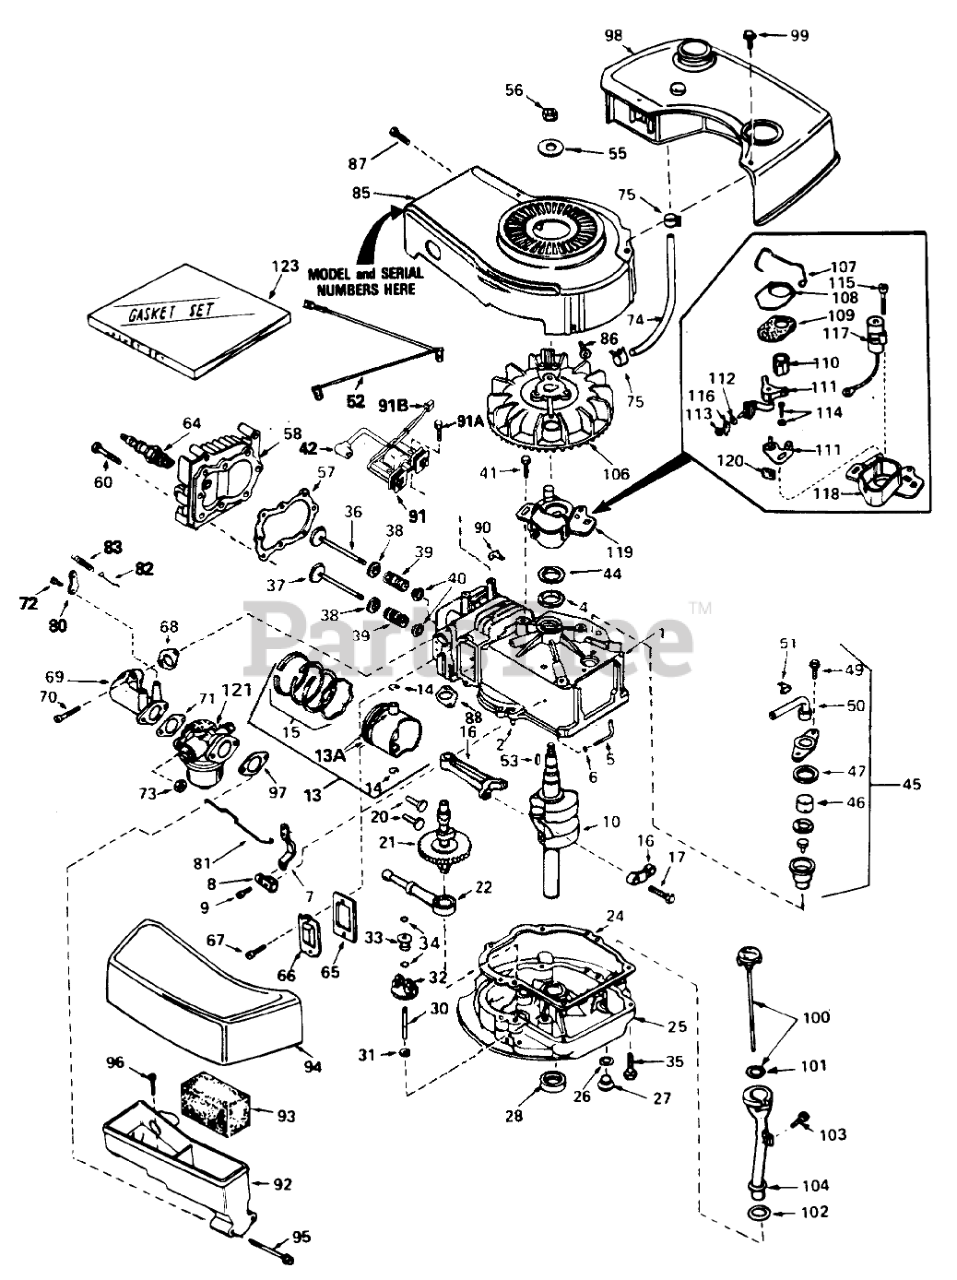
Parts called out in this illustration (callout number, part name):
1	Cyiinder Assy. (Incl. Ref. #2, 4 & 105)
2	Pin-Dowel
4	Seal-Oil
5	Rod, Governor (Incl. Ref. #6)
6	Washer-Flat
7	Governor Lever
8	Clamp-Lever, Governor
9	Screw
10	Crankshaft
13	Piston, Pin & Ring Assy. (Std.)(Incl. Ref. #13A, 14 & 15)
13	Piston,Pin & Ring Assy. (.010 over-size)(Incl. Ref. #13A, 14 & 15)
13	Piston, Pin & Ring Assy. (.020 over-size)(Incl. Ref. #13A, 14 & 15)
13A	Piston & Pin Assy. (Std.)(Incl. Ref. #14)
13A	Piston & Pin Assy. (.010 over-size)(Incl. Ref. #14)
13A	Piston & Pin Assy. (.020 over-size)(Incl. Ref. #14)
14	Ring-Retaining, Piston Pin
15	Ring Set Piston (Std.)
15	Ring Set Piston (.010 Oversize)
15	Ring Set Piston (.020 Oversize)
16	Rod Assy., Connecting (Incl. Ref. #17)
17	Bolt-Rod, Connecting
20	Lifter-Valve
21	Camshaft(Mech.Comp. Release)
22	Oil Pump ASM
24	Gasket, Mounting
25	Flange Assy., Mounting (Incl. Ref. #26 thru 30)
26	Gasket-Oil Drain
27	Plug Oil Drain
28	Seal Oil
30	Shaft-Governor
31	Washer-Flat
32	Gear Assy., Governor (Incl. Ref. #31)
33	Spool-Governor
34	Ring-Retaining
35	Screw (1/4-20 x 1-1/4)
36	Valve, Intake (Std.)(Incl. Ref. #40)
36	Valve, Intake (1/32" oversize)(Incl. Ref. #40)
37	Valve, Exhaust (Std.)(Incl. Ref. #10)
37	Valve, Exhaust (1/32" oversize)(Incl. Ref. #40)
38	Cap-Upper Valve Spring
39	Spring-Valve
40	Cap-Valve, Spring
42	Cover-Spark Plug
44	Gasket Stator
45	Breather Assy. (Incl. Ref. #46 thru 51)
46	Element-Breather
47	Gasket-Breather
49	Screw (10-24 x 9/16)
50	Tube, Breaker
51	Clip, Breather
52	Wire, Ground
53	682488 LB GRASS HI-
55	Washer-Belleville
56	Nut-Flywheel
57	63573 GIL 42 SNWTHW
58	Head-Cylinder
60	Screw (5/16-18x1-1/2)
64	Plug, Spark (J17LM or equiv.)
64	Plug, Spark (Champion RCJ-8)
65	Gasket-Breather
66	Cover-Valve
68	Gasket-Intake
69	Pipe, intake (Incl. Ref. #68)
70	Screw (1/4-20 x 1)
71	Gasket-Carburetor
72	Screw
73	Nut and Lock Washer (1/4-28)
74	Line-Fuel
75	Clamp-Line, Fuel
80	Lever-Adjusting, R P M
81	Link-Throttle
82	Link Governor Spring
83	Spring Governor
85	Housing Blower
86	Screw
87	Screw (10-24 x 9/16)
88	Gasket Exhaust
90	Clip-Wire
91	Lamination & Coil Assy. (Incl. Ref. #42 & 91B)
91A	Screw
91B	Terminal
92	Body Air Cleaner
93	Filer, Air
94	Cove, Air Cleaner
95	Screw Fil Hd.
96	Screw, Hex Hd.
97	Gasket-Air Cleaner
98	Tank, Fuel
99	Screw (10-32 x 35/64)
100	Dipstick, Oil (Incl. Ref. #101)(Twist Lock)
103	Screw (10-32 x 1/2)
104	Tube-Oil Fill
106	FIywheel
107	Spring Breaker Box
108	Cover-Dust
109	Gasket, Dust Cover
110	Cam-Breaker
111	Breaker Assy.
114	Breaker Screw
115	Condenser Screw
116	Terminal, Ground
117	Condenser
118	Stator Plate
119	Stetor Assy. (Incl. Ref. #107, 111 thru 118 & 120)
120	Felt,Cam Wiper
121	Carburetor (Incl. Ref. #71 )
123	Gasket Set (Incl. Items Marked )
